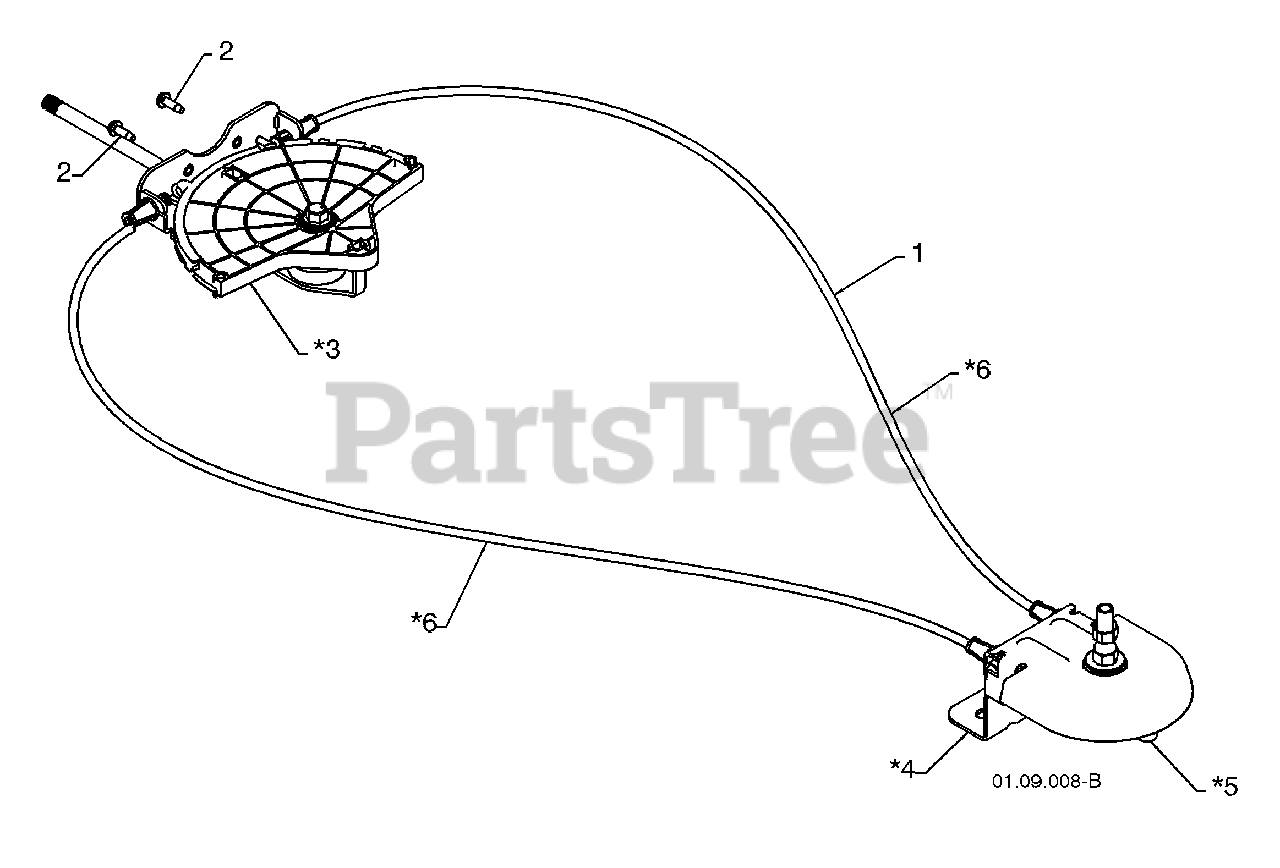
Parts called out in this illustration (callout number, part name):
1	LEVER/CABLE ROTATOR ASSEMBLY GRAY
2	SCREW 10-24 X .625
3	ROTATOR HEAD
4	ROTATOR PIVOT BRACKET
5	PULLEY PIVOT
6	CABLE ASSEMBLY GRAY
